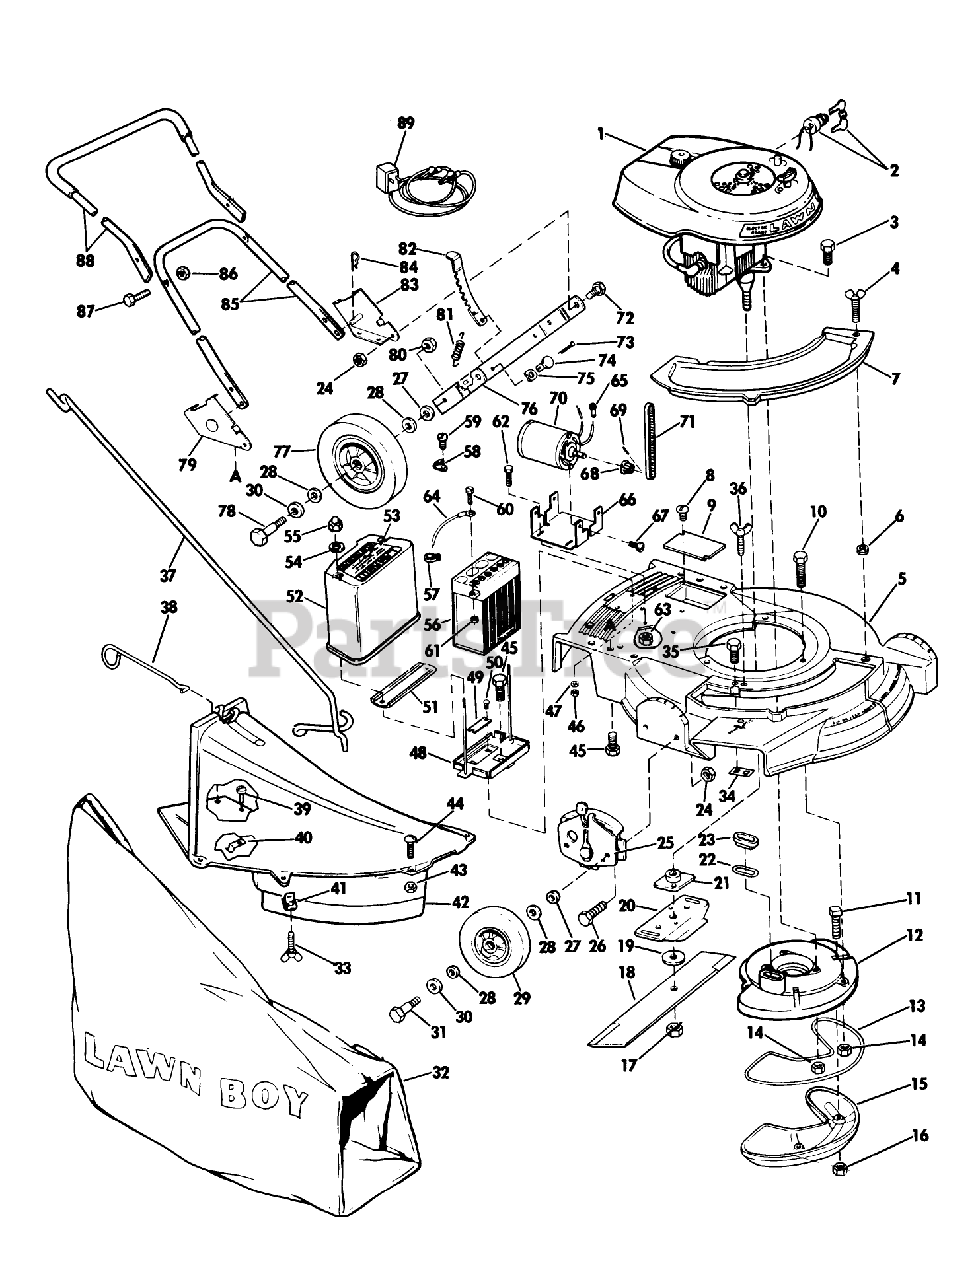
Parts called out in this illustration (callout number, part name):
16	LOCKNUT E
17	NUT-BLADE
21	PLATE AND COLLAR ASM
22	GASKET S
27	WASHER WROUGHT
31	BOLT WHEEL
32	89802 LB WHOLE GOODS
41	SPEED NUT ARDEN
42	Chute Skirt Assembly (Includes Hardware)
53	Decal-Instructions
55	PALNUT S
57	RETAINER ARDEN
59	SCREW S
62	SCREW S
72	BOLT-SHOULDER
75	WASHER SPRING LAR
80	LOCKNUT
81	SPRING N.A.S
84	HAIR PIN
